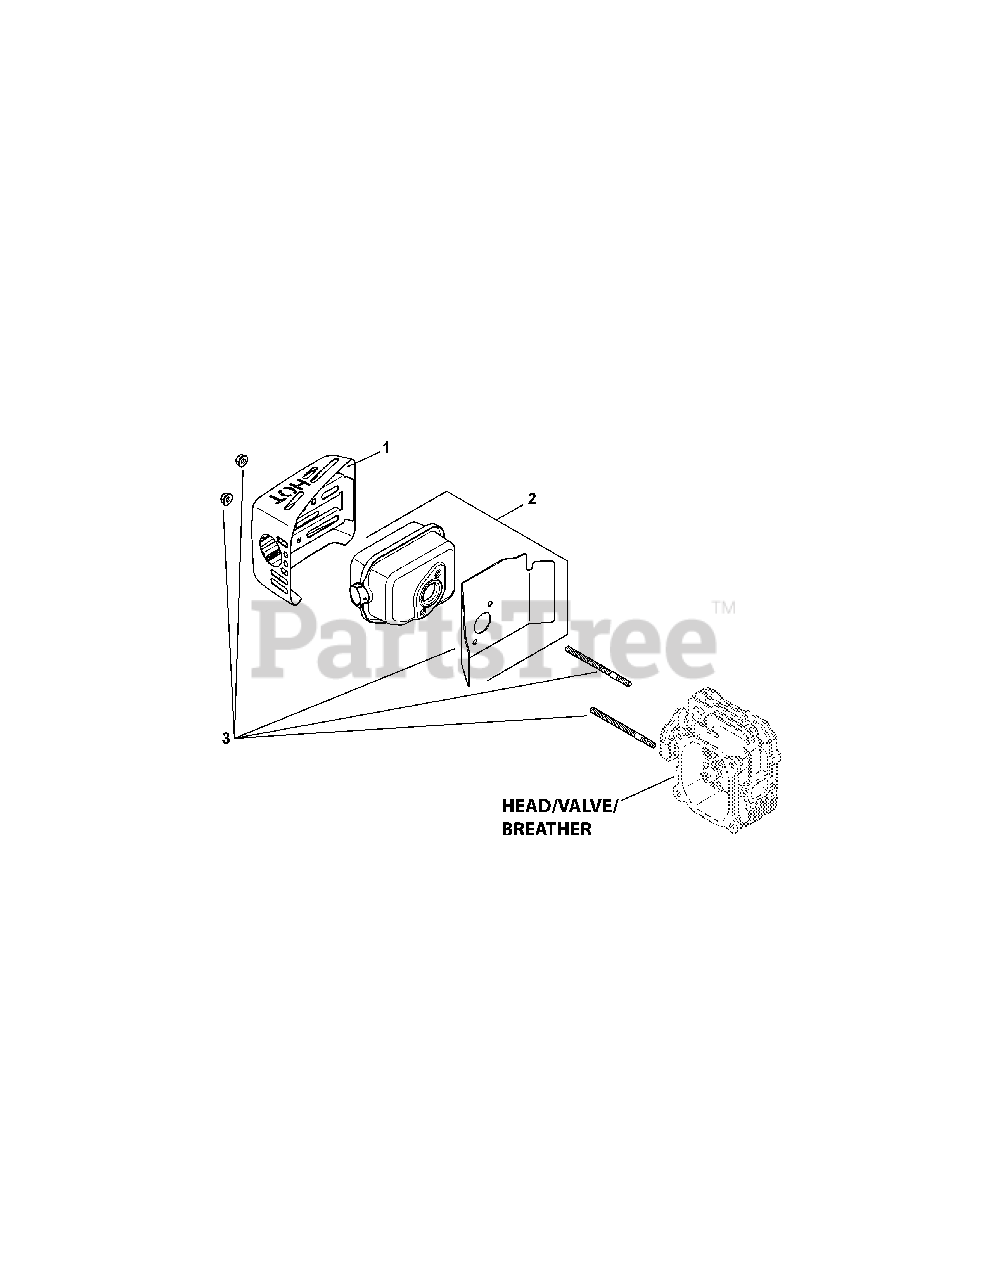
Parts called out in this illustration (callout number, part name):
1	Shield, Muffler
2	Kit, Muffler (Includes Muffler Gasket)
3	Kit, Exhaust Hardware
